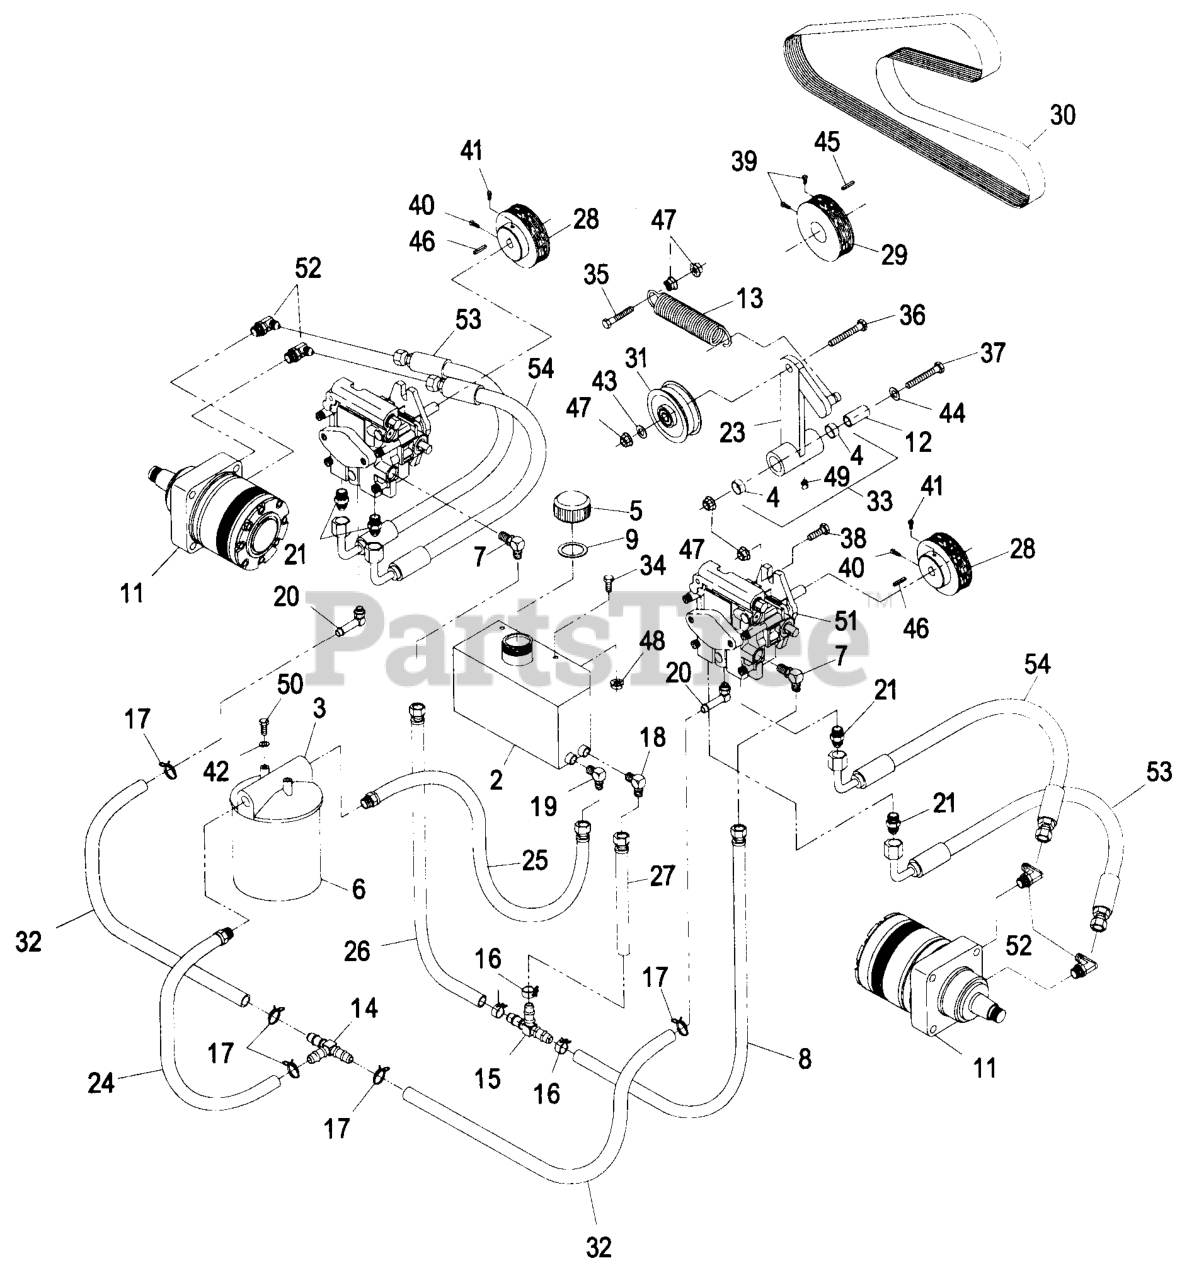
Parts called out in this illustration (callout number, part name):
1	HOSE-PRESSURE, HIGH
3	FILTER-HEAD
4	SLEEVE-BEARING
7	FITTING-90 DEG
8	LOW PRESSURE HOSE ASM
9	GASKET-CAP, TANK
10	FITTING-HYD, 45 DEG
11	MOTOR-WHEEL
12	BUSHING-PIVOT, IDLER
13	SPRING-EXTENSION
14	FITTING-TEE, HOSE
15	FITTING-TEE, HOSE
16	CLAMP-HOSE
17	CLAMP-HOSE
18	FITTING-ELBOW
19	FITTING-ELBOW
20	FITTING
21	FITTING-STRAIGHT
24	HOSE ASM
25	HOSE ASM
26	HOSE ASM
27	HOSE ASM
30	BELT,POLY-V 5K
31	SHEAVE-IDLER
32	HOSE-PRESSURE, LOW
33	BEARING ARM ASM
37	SCREW-HH
39	SCREW-SET
41	SCREW-SET
42	WASHER-LOCK
52	FITTING-90 DEG
53	HOSE-LOWER
54	HOSE-UPPER
